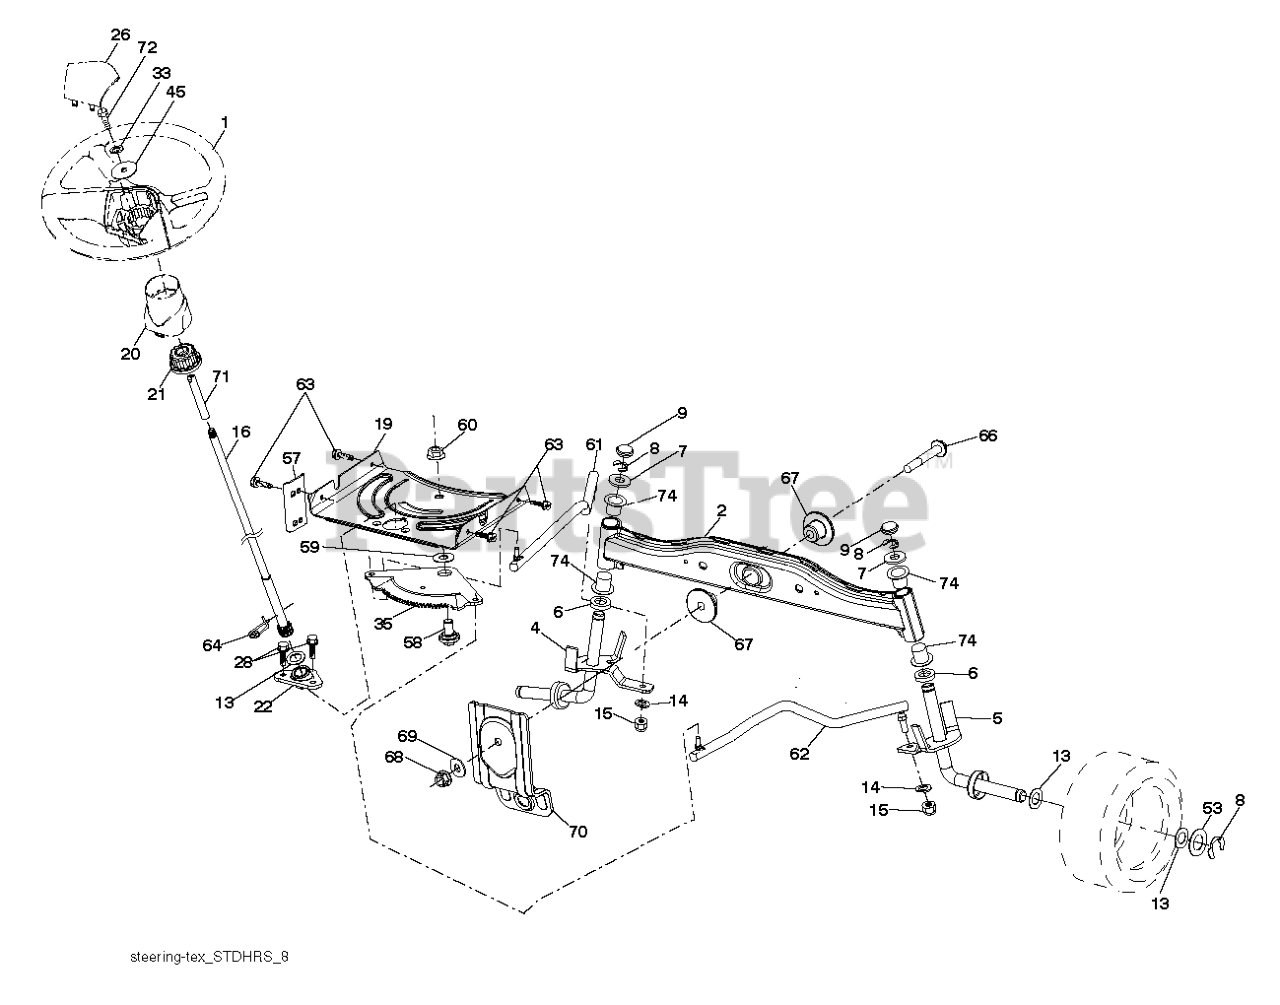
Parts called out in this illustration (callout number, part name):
1	RP WHEEL.STEER.HUSQ.PREM.OVMLD
2	AXLE HALF ASM-WELDED
4	SPINDLE.STEERING.ASM.LH.13".TI
5	SPINDLE.STEERING.ASM.RH.13".TI
6	THRUST WASHER
9	CAP.SPINDLE.BLACK
14	WASHER, LOCK 3/8
15	NUT CROWNLOCK 3/8-24
16	SHAFT.STEER.3/4.PLATED.TEX
19	PLATE.STEER.DDL.NLT/NG
20	BOOT, STEERING
21	ADAPTER, WHEEL STNG..
22	STEERING.SUPT.LOWER.
26	RP INSERT.CAP.WHL.STRG.HUSQ.
28	SCREW, 3/8-16X3/4
33	WASHER.LOCK.HVY.HLCL.SPR.5/16
35	GEAR.SECTOR.PLATE.DDL.
45	WASHER.11/32
53	WASHER.HARDENED
57	BRACKET.UPSTOP.TEX
58	BOLT.SHOULDER.SECTOR.P
59	WASHER.THURST.SECTOR.S
60	NUT FLANGE LOCK 5/8-11
61	DRAGLINK.LH.BALLSTUD.D
62	DRAGLINK.RH.BALLSTUD.D
63	SCREW
64	RETAINER.CLIP.SPRING.S
66	BOLT HEX FGHD 7/16-14 X 3 SERR
67	BUSHING.PM.FRONT AXLE
68	NUT.LOCK.FLANGE.7/16
69	WASHER.1.5X.505X.118
70	BRACKET.SUSP.MWR.FRT.30"SRD
71	SHAFT.EXTEN.STRG.SPLINE
72	BOLT 5/16-18 X 4 W/PATCH
74	BRNG T
